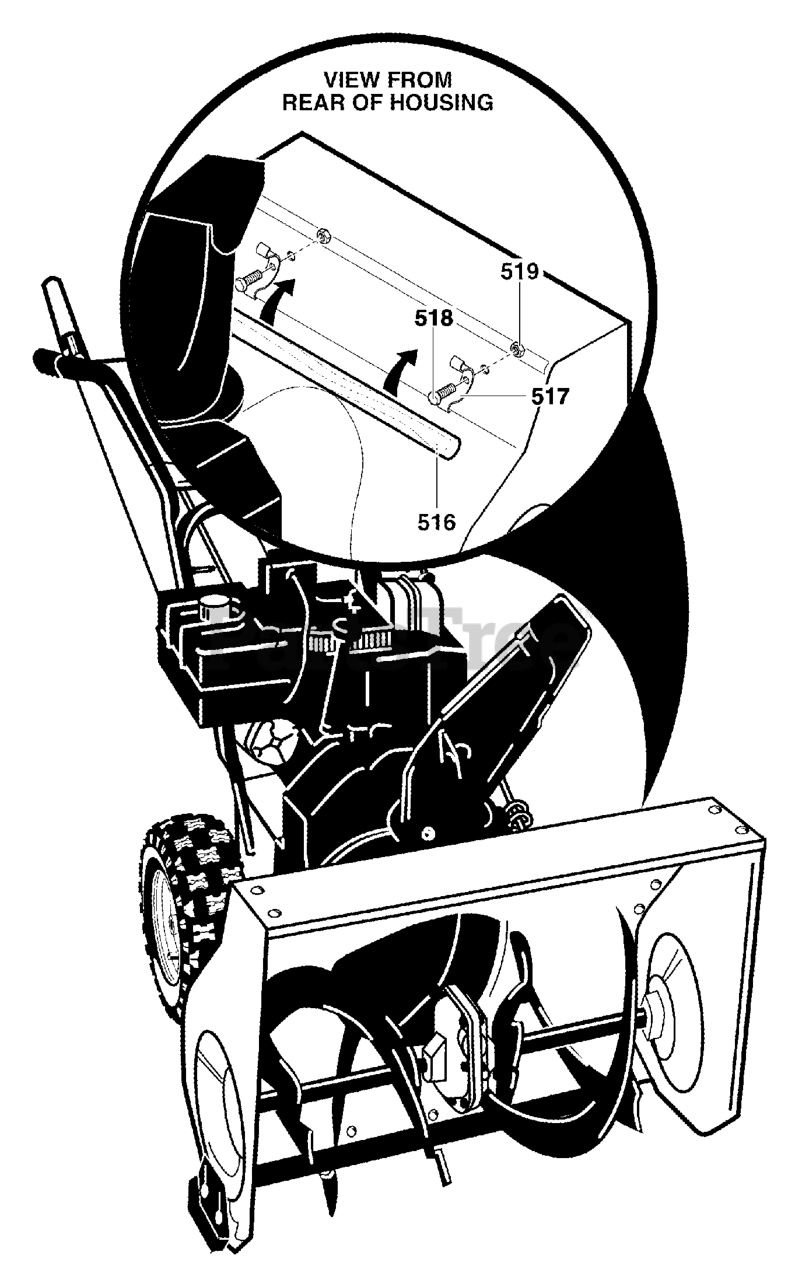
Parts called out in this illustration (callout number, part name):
516	STICK, CLEARING
517	CLIP, RETAINER
518	SCREW
